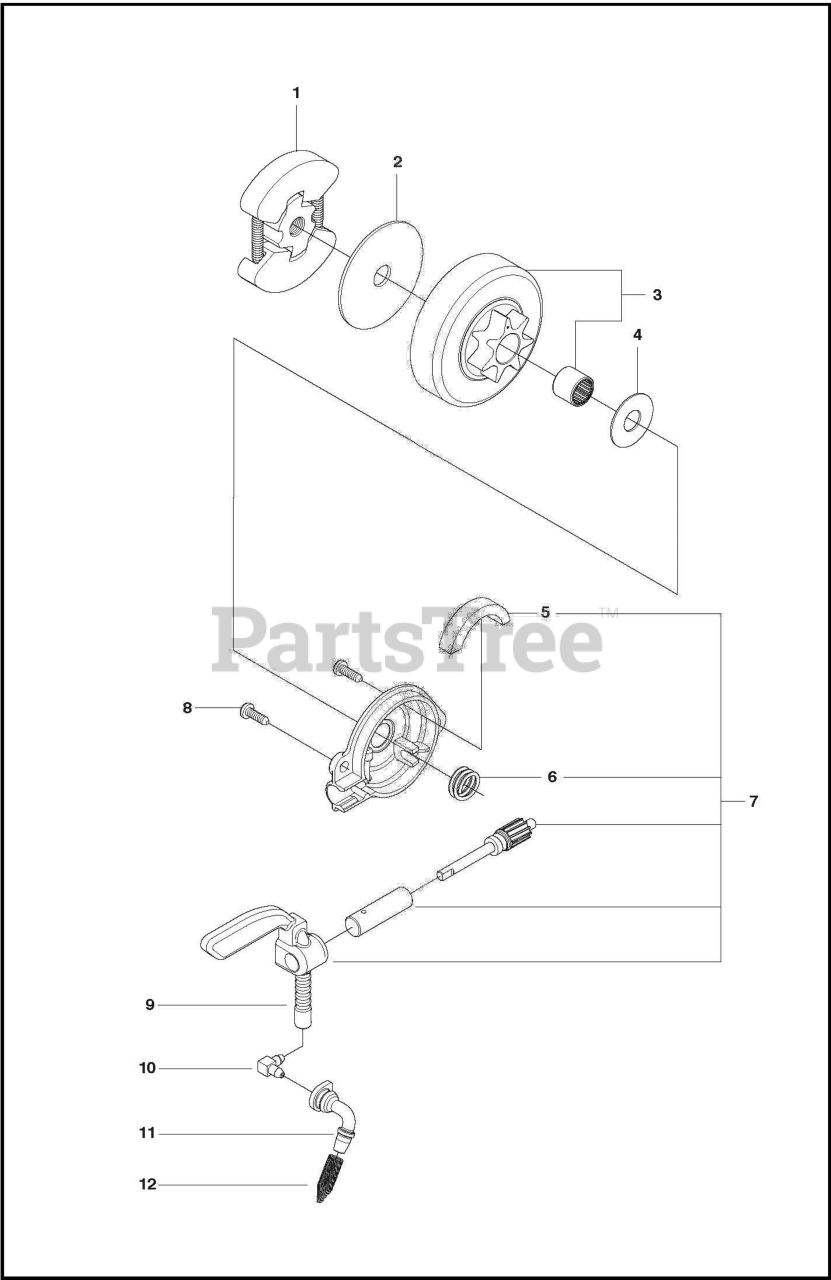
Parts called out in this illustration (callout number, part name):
1	CLUTCH ASSEMBLY
2	FRICTION DISC,CLUTCH 36/41
3	CLUTCH DRUM ASSY
4	WASHER
5	SEAL
6	WORM GEAR
7	OIL PUMP ASSY
9	BLOCK OIL
10	ELBOW
11	SEAL PICKUP
12	SCREEN/FILTER
